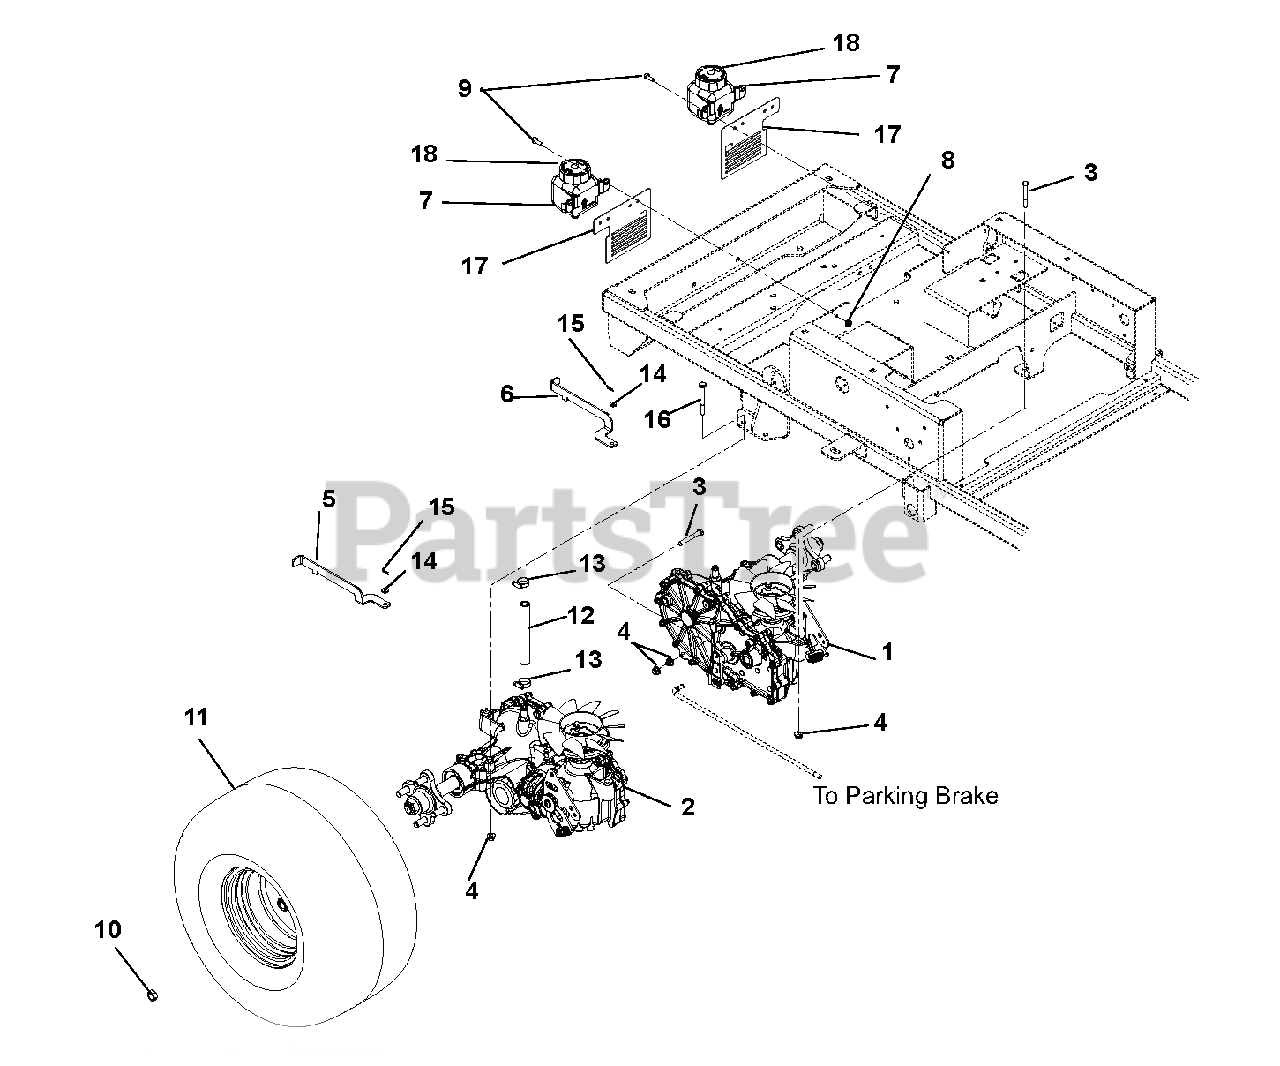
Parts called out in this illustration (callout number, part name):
1	TRANSAXLE, ZT2800 LH
2	TRANSAXLE, ZT2800 RH
3	@BLT-HEX .31-18X2.25 GR5 YWZC
4	@NUT-LK-NYL-FLG .31-18 YWZC
5	DUMP VALVE, RH
6	DUMP VALVE, LH
7	TANK, EXPANSION
8	@NUT-LK-TOP-FLG .25-20 YWZC
9	@BLT-HEX .25-20X.75 GR5 YWZC
10	WHEEL NUT .500-20 YZ
11	TIRE/WHEEL ASM, 20X8.0-8 (SQ)
12	HOSE, OIL RESERVOIR
13	CLAMP,.88 DIA. HOSE
14	WSHR-FL-STL .265X.50X.087YWZC
15	PIN-HAIR INT .06X.18X.77
16	@BLT-HEX .31-18X2.75 GR5 YWZC
17	BRKT, REAR FAN GUARD
18	CAP, HYDRO RESERVOIR REPLAC.
